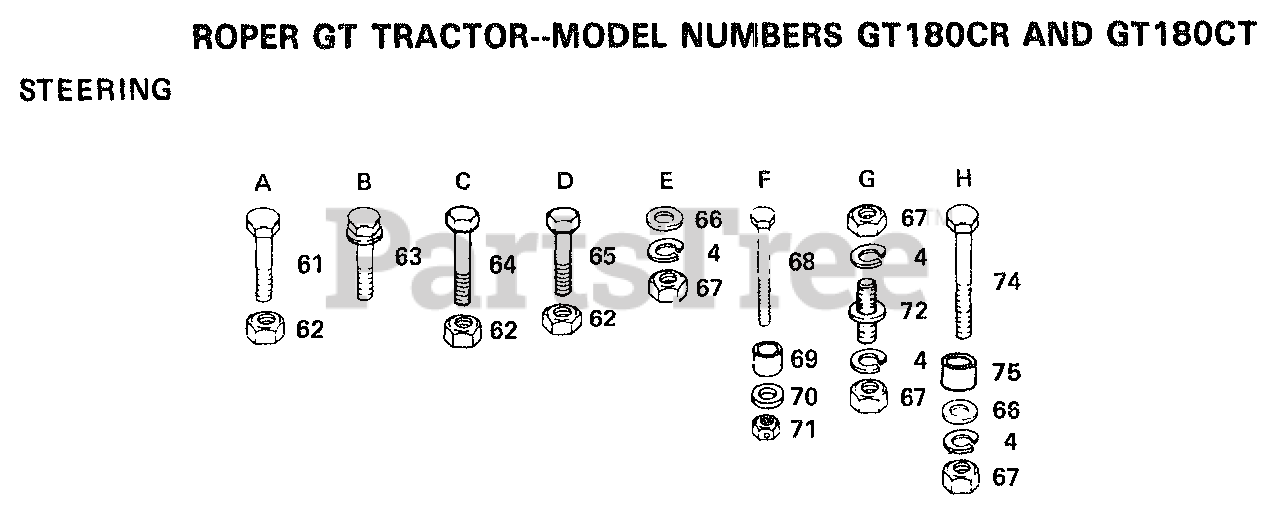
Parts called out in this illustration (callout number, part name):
4	LOCKWASHER
63	SCREW
64	BOLT
65	BOLT
66	WASHER
67	NUT.HEX.3/8-16UNC
69	BUSHING LT
70	WASHER
75	SPLIT SPACER YTV
